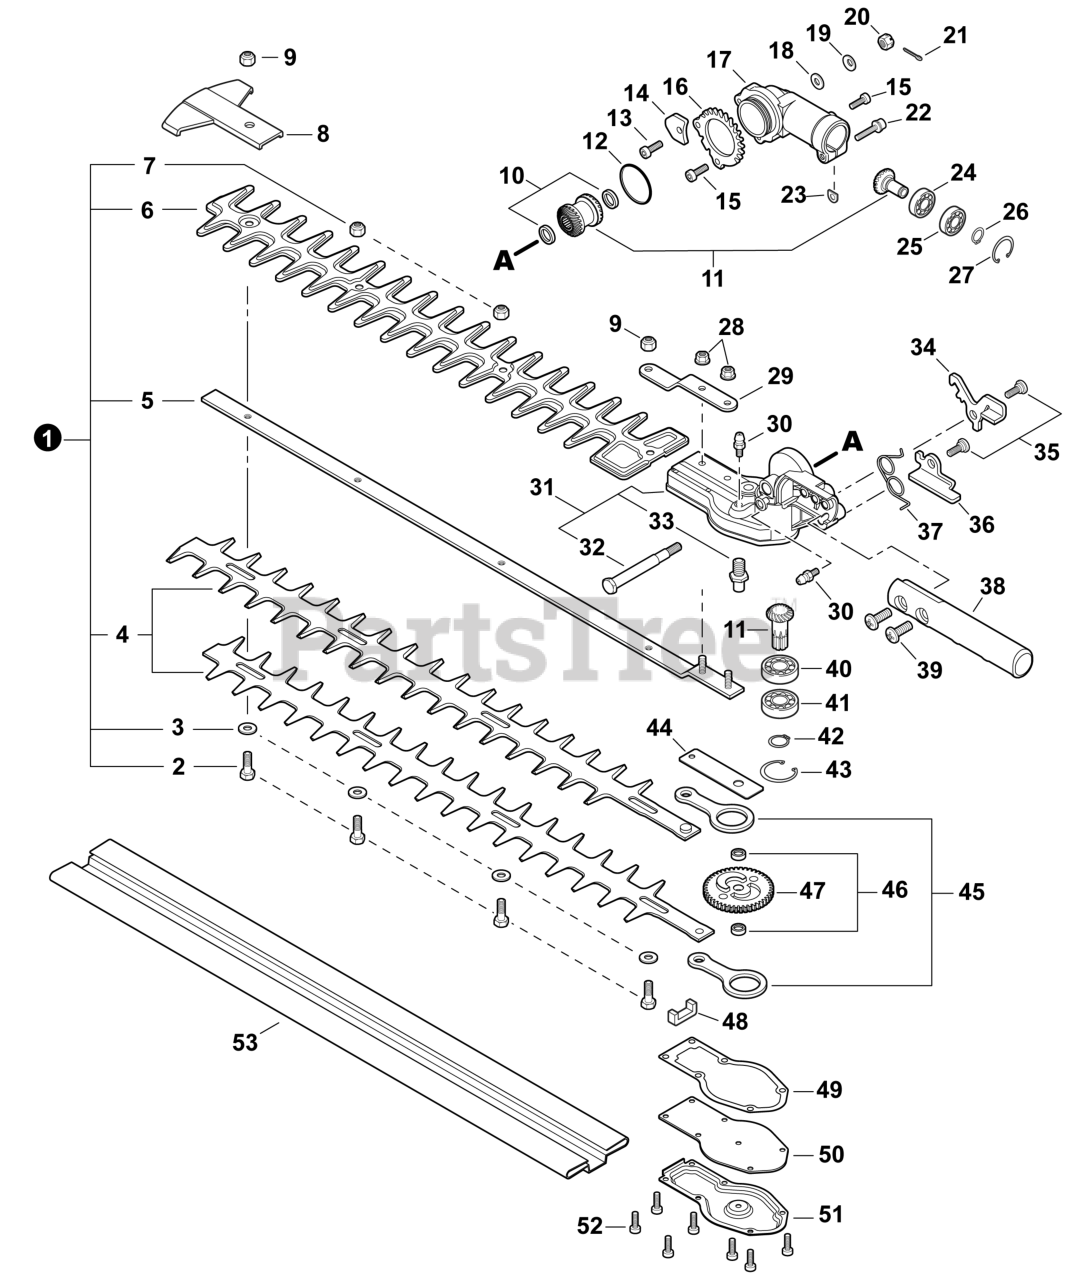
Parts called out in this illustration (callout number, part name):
1	CUTTER ASSY, 22"
2	BOLT M6×20
3	WASHER M6
4	CUTTER 22"
5	GUIDE BAR 22"
6	GUARD, CUTTER BLADE
8	GUARD, TIP
10	COLLAR Ø16ר10×L= 2
11	GEAR SET
13	SCREW M5×16
14	PLATE, STOPPER
15	BOLT 5×12
16	RING, LOCKING
17	HOUSING, UPPER GEAR CASE
18	WASHER 6.5×13×1
19	WASHER, CONE M6
21	PIN, COTTER Ø1.6×15
22	BOLT M5×25
23	D-WASHER
24	BEARING, BALL 609
25	BEARING, BALL 609ZZ
26	RING, SNAP Ø9
27	RING, SNAP 24
28	NUT, FLANGE M5
29	BRACKET, CUTTER
30	FITTING, GREASE
31	GEAR CASE HOUSING ASSY
33	MAINSHAFT
34	LEVER, LOCK
35	BOLT M6
36	RELEASE, LOCK
37	SPRING, TORSION
38	LEVER, ADJUSTMENT
39	SCREW, TRUSS M6×20
40	BEARING, BALL 6001
41	BEARING, BALL 6001ZZ
42	RING, SNAP Ø12
43	RING, SNAP 28
44	PLATE, GUIDE
46	SPACER Ø11ר8×3.4
47	GEAR, CAM
48	PACKING, FELT
49	GASKET, GEAR CASE
51	COVER, GEAR CASE
52	BOLT 4×10
53	SCABBARD
